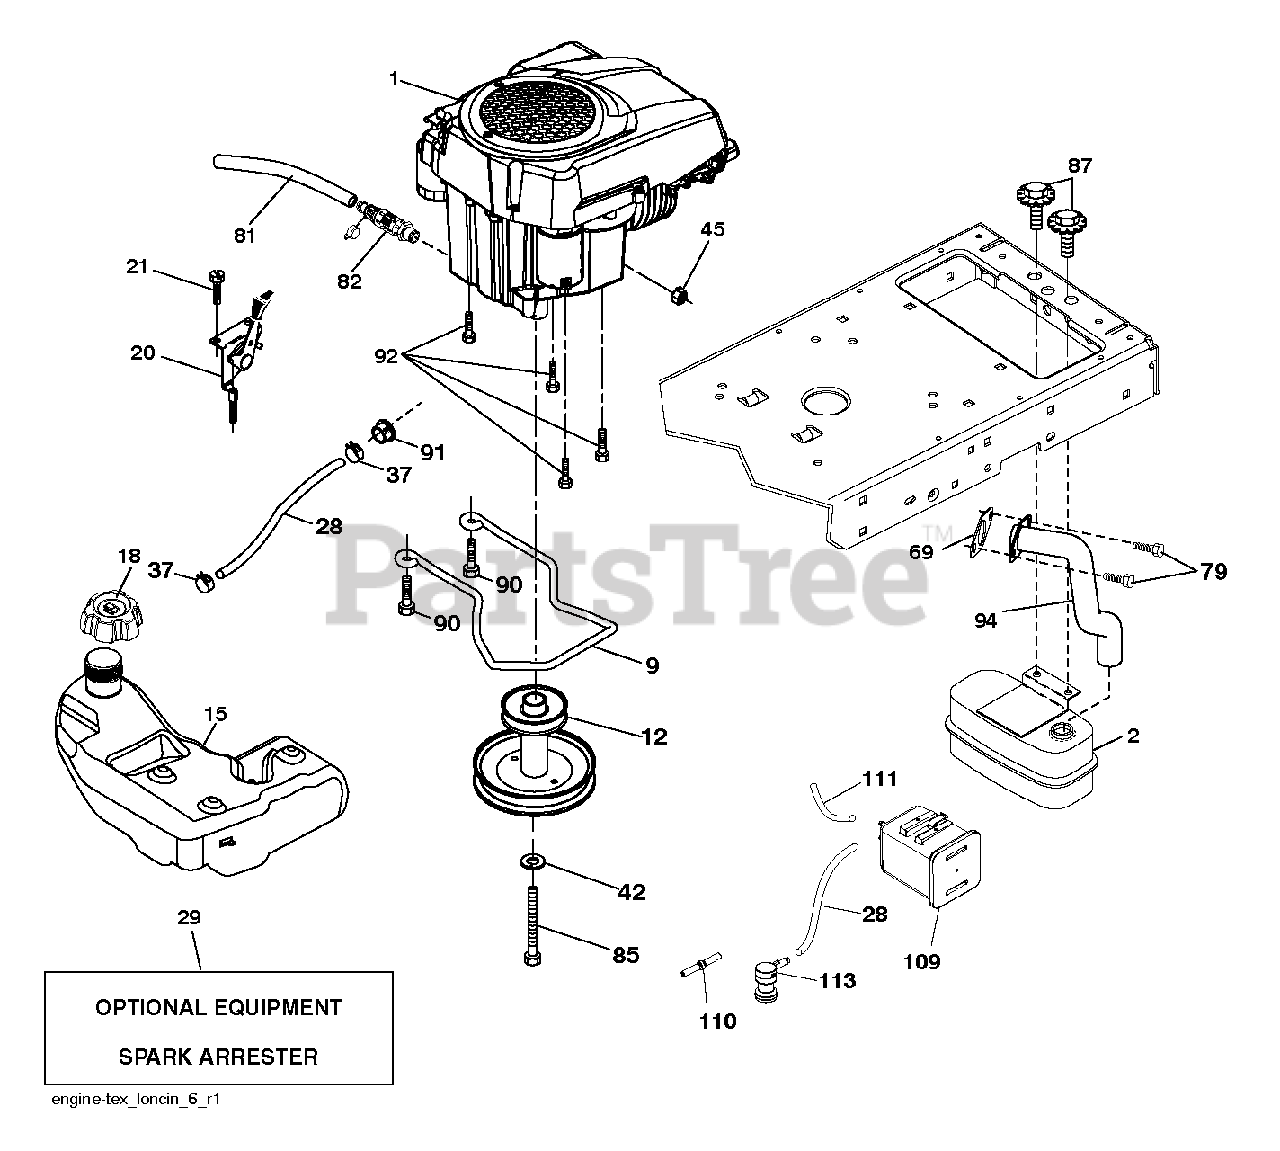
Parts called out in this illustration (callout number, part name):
2	Muffler Assembly, Single
9	KEEPER.BELT.ENG.4.25"2.BLT.431
12	ENGINE.PULLEY
15	Fuel Assembly Tank, 3 Gallon
18	FUEL.CAP.ASM.3"RAT.TETH.1WAY.H
20	CONTROL.TH/CK.C.
21	SCREW.#10 X 0.750.BOS
28	LINE.FUEL.20"FRONT.EMI
29	KIT.SPARK ARRESTOR 794945 B&S
37	HOSE CLAMP
42	WASHER 7/16 LOCK
45	NUT HEXAGON WITH FLANGE, SERRA
69	GASKET GASKET.EXHAUST. LONCIN
79	SCREW.SOCKET.HEAD.5/16-18
81	TUBE, DRAIN OIL ASM.
82	VALUE.OIL.DRAIN
85	BOLT.HEX.7/16-20X4.GR5.1.5BLUE
87	BOLT, 5/16-18 X 1 3/4
90	SCREW 3/8-16X1
91	BUSHING.1.375OD
92	SCREW 3/8-16X1
94	TUBE TUBE.EXHAUST.LONCIN 608.T
109	CANNISTER, CARBON
110	VALVE.ASM.ANTI-SLOSH
111	RP PURGE LINE
113	VALVE.SLANT.CARTRDG.90 DEG.TEX
